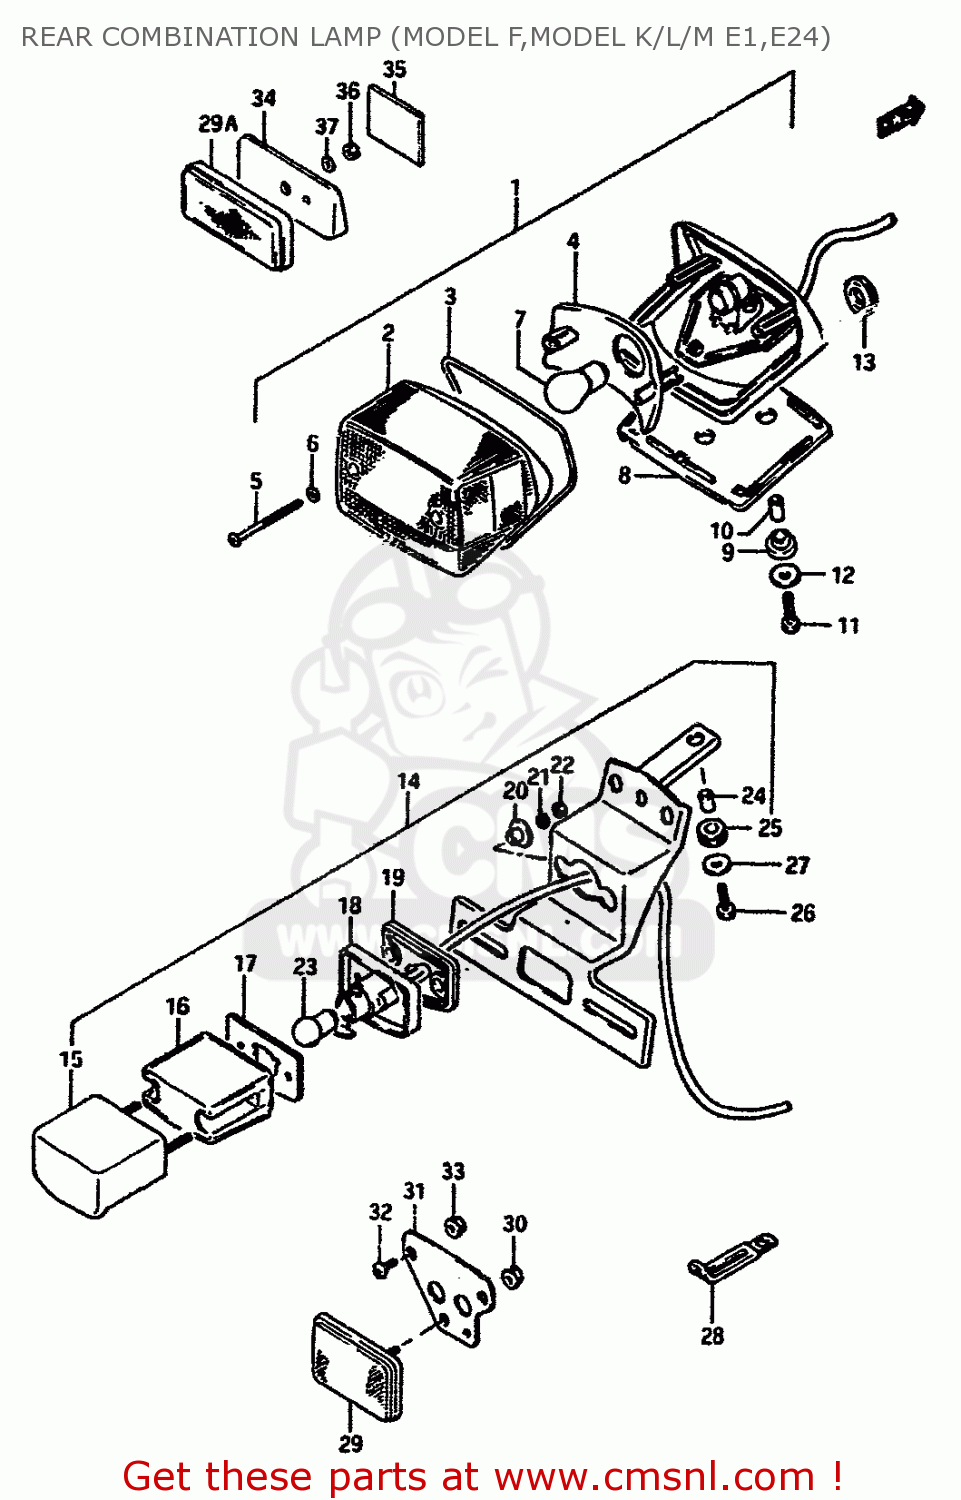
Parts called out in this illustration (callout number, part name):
1	LAMP ASSY,RR COMBINATION
2	LENS
3	GASKET (NAS)
4	REFLECTOR
5	SCREW
6	GASKET (NAS)
7	BULB(12V21/5W)
8	CUSHION
9	CUSHION
10	SPACER
11	BOLT
12	WASHER
13	GROMMET
14	LAMP ASSY,LICENSE
15	COVER,LICENSE LAMP
16	LENS
17	GASKET,LICENSE LAMP (NAS)
18	HOUSING,LICENSE LAMP
19	CUSHION
20	SPACER
21	WASHER,LOCK 4M
22	NUT
23	BULB
24	SPACER
25	CUSHION
26	BOLT,M6X1X20
27	WASHER
28	CLAMP L:35
29	REFLEX REFLECTOR,REAR
29A	REFLEX REFLECTOR ASSY,RR
30	NUT
31	BRACKET
32	SCREW 5X10
33	NUT
34	SPACER
35	COVER,HARNESS
36	NUT 5MM
37	WASHER
